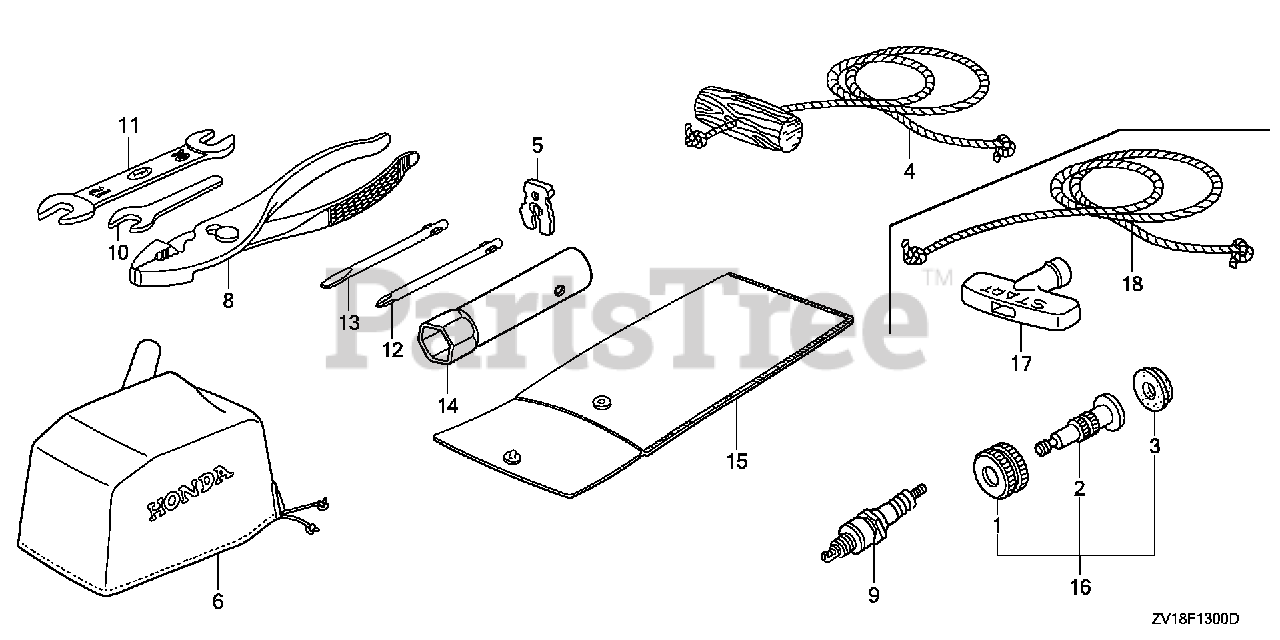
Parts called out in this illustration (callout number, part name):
1	NUT, WATER MOUTH Use from Frame SN 1000929.
2	JOINT, WATER HOSE
3	SEAT, WATER MOUTH Use from Frame SN 1000929.
5	CLIP, EMERGENCY LOCK
6	COVER, BODY
7	TOOL KIT
8	PLIERS (135) (RIKEN)
9	SPARK PLUG (W16EPR-U)
9	SPARK PLUG (BPR5ES) (NGK)
10	WRENCH (8MM) (OPEN END)
11	WRENCH (10X12) (OPEN END)
12	SCREWDRIVER 1, PHILLIPS (NO.2)
13	SCREWDRIVER 3, STRAIGHT SLOT (NO. 2)
14	WRENCH, BOX (P21)
15	BAG, TOOL (160MM)
17	GRIP, STARTER
18	ROPE, RECOIL STARTER (1300MM)
